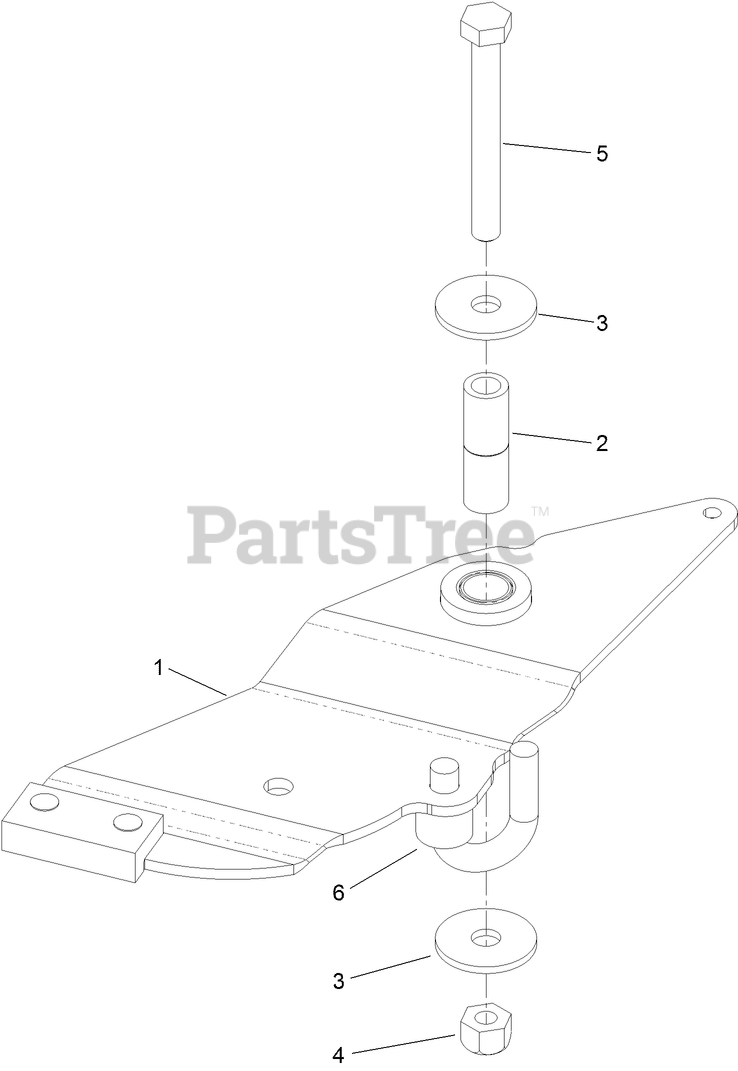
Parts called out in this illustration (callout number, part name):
1	BRAKE ARM ASM
2	Spacer-Brake
3	WASHER-PIVOT
4	NUT-LOCK, NI
5	SCREW-HH
6	HOSE-COOLANT
